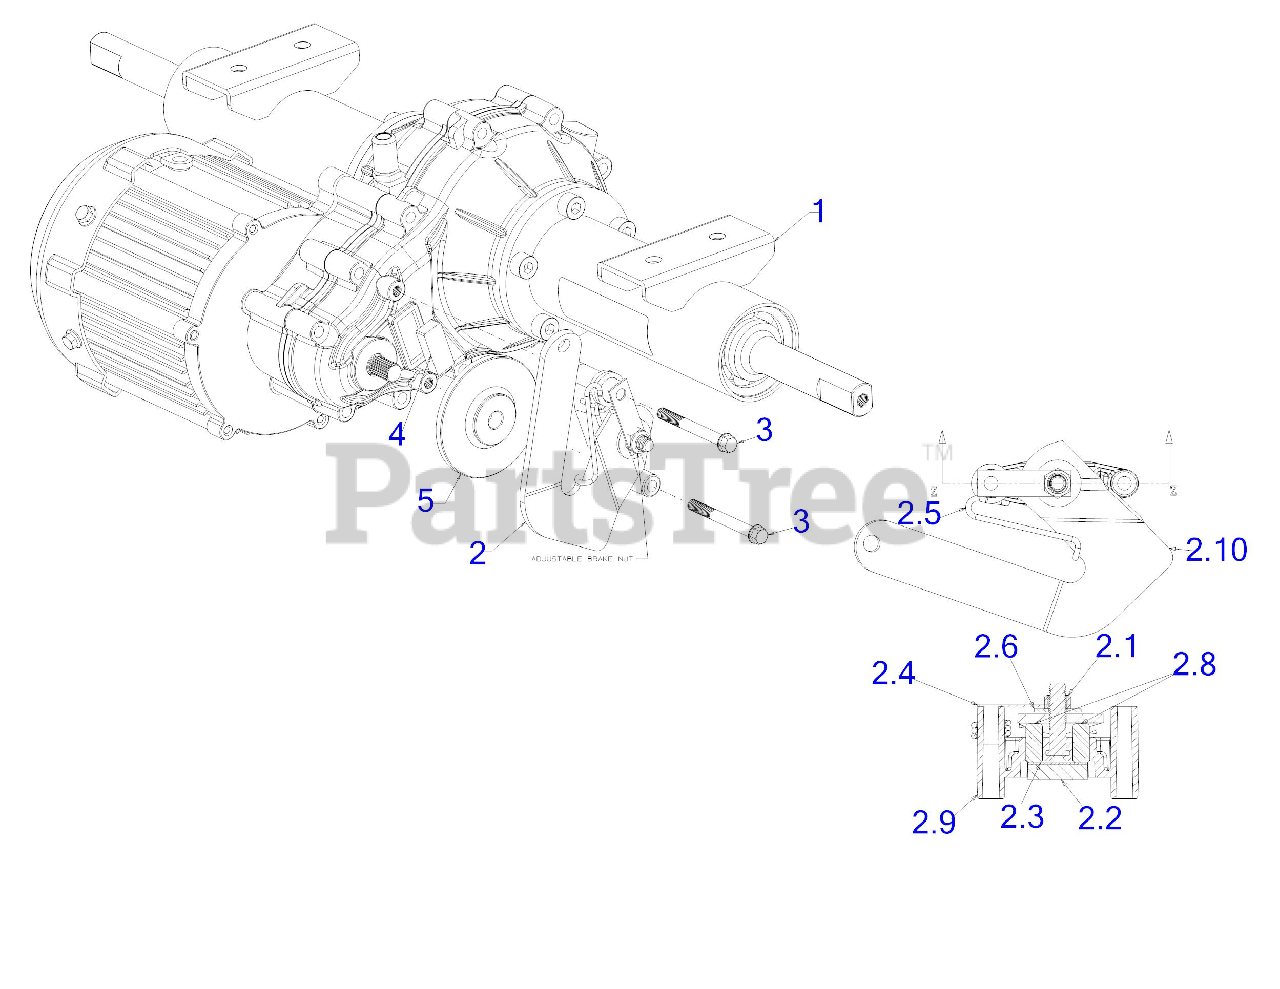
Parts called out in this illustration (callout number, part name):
1	TRANSMISSION ASSEMBLY
2	YOKE BRAKE ASSEMBLY
2.1	ACTUATOR ARM
2.2	BRAKE PUCK
2.3	PUCK PLATE
2.4	ANTI ROTATION BRACKET
2.5	TORSION SPRING
2.6	FLAT WASHER
2.8	ACTUATING PIN
2.9	BRAKE YOKE
3	SCREW (M6-1 55 CL8.8)
4	BRAKE PUCK
5	BRAKE DISC
